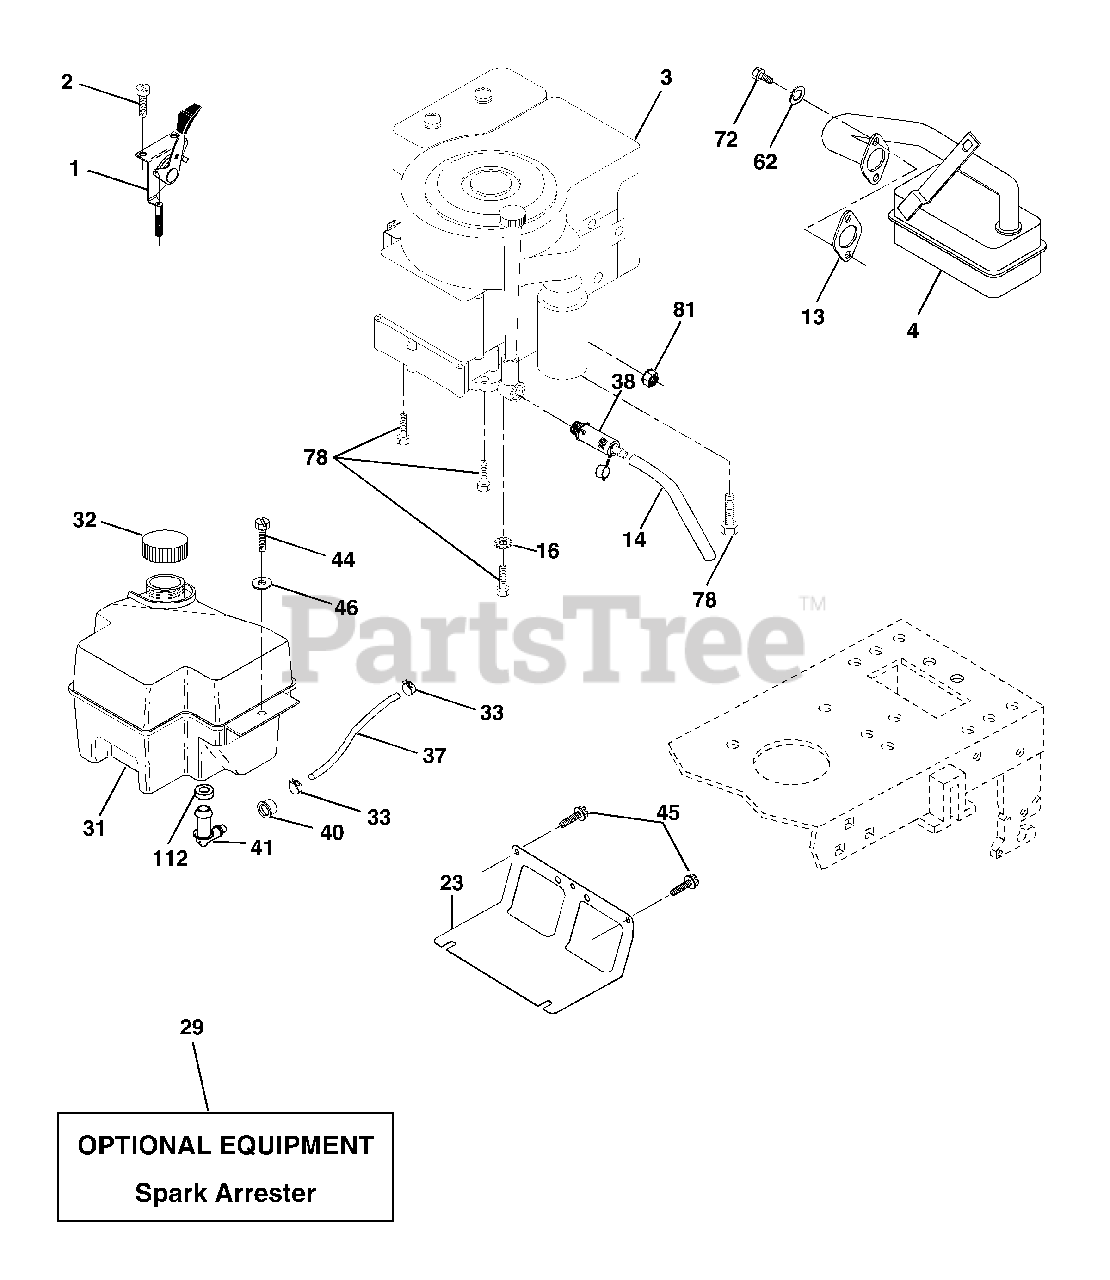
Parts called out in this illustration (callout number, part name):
1	Control Th/ch Flag
2	Screw Hex Thd Cut 1/4-20 1/2
4	Muffler Exhaust
11	Washer Lock 5/16
13	Gasket Muffler
14	Tube Drain Oil Easy
23	Shield Brn/Dbr Guard
29	Arrestor Spark
31	Tank Fuel Front 2 00
32	Cap Fuel
33	Clamp Hose Black
37	Line Fuel 20"
38	Plug Drain Oil Easy
40	Bushing Snap Nyl Blk Fuel Line
41	Stem Tank Fuel
44	Screw Hex wsh Thdrol 1/4-20x3/4
45	Screw Hex Wsh Thdrol 3/8-16 x 3/4
46	Washer 9/32 X 7/8 X 16 Ga
62	Washer Lock Ext Tooth 3/8
72	Screw Hex 5/16-18 x 3/4
78	Screw 3/8-16 x 1-1/4
81	Nut Keps Hex 1/4-20 Unc
112	Bushing
